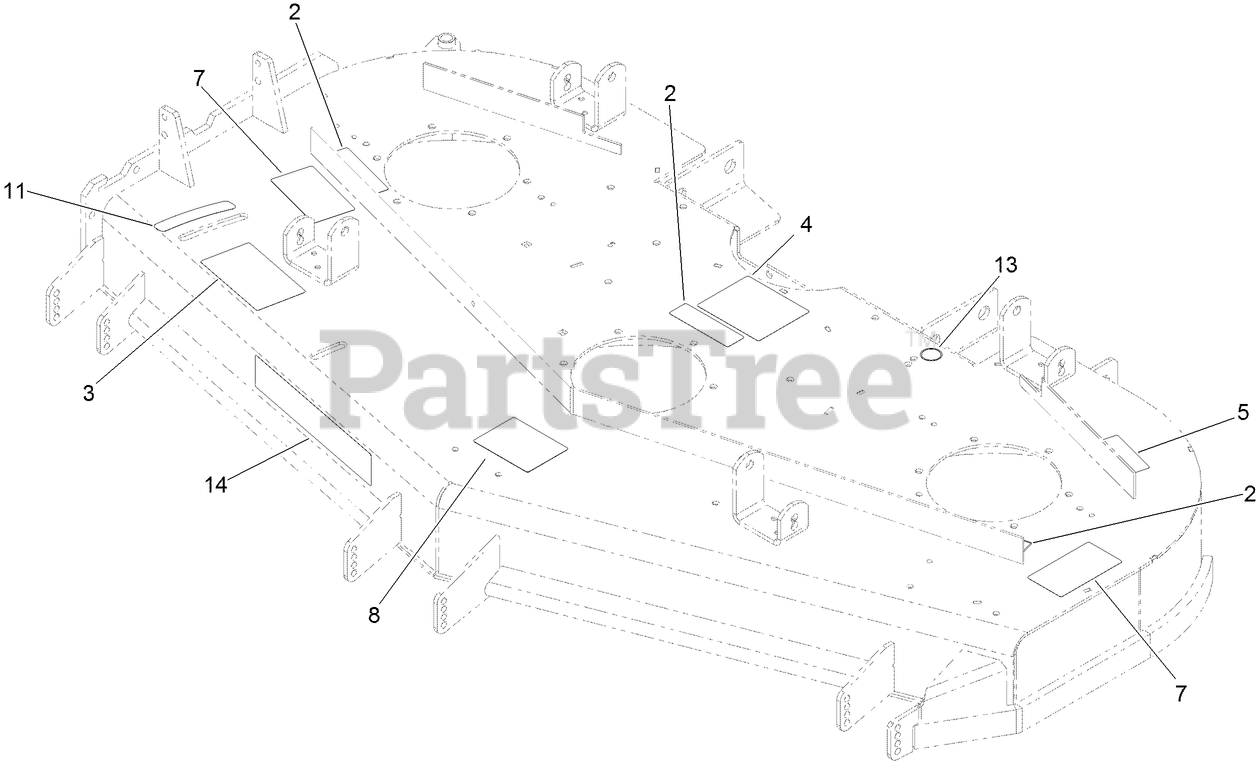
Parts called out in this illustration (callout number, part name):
2	DECAL-COVER, MISSING
3	DECAL-ADJUSTMENT, BAFFLE
4	DECAL-ROUTING, BELT
5	DECAL-BOLT TORQUE
7	DECAL-DANGER
8	DECAL-SCALP, ANTI
11	DECAL-SETTING, BAFFLE
13	DECAL-GREASE
